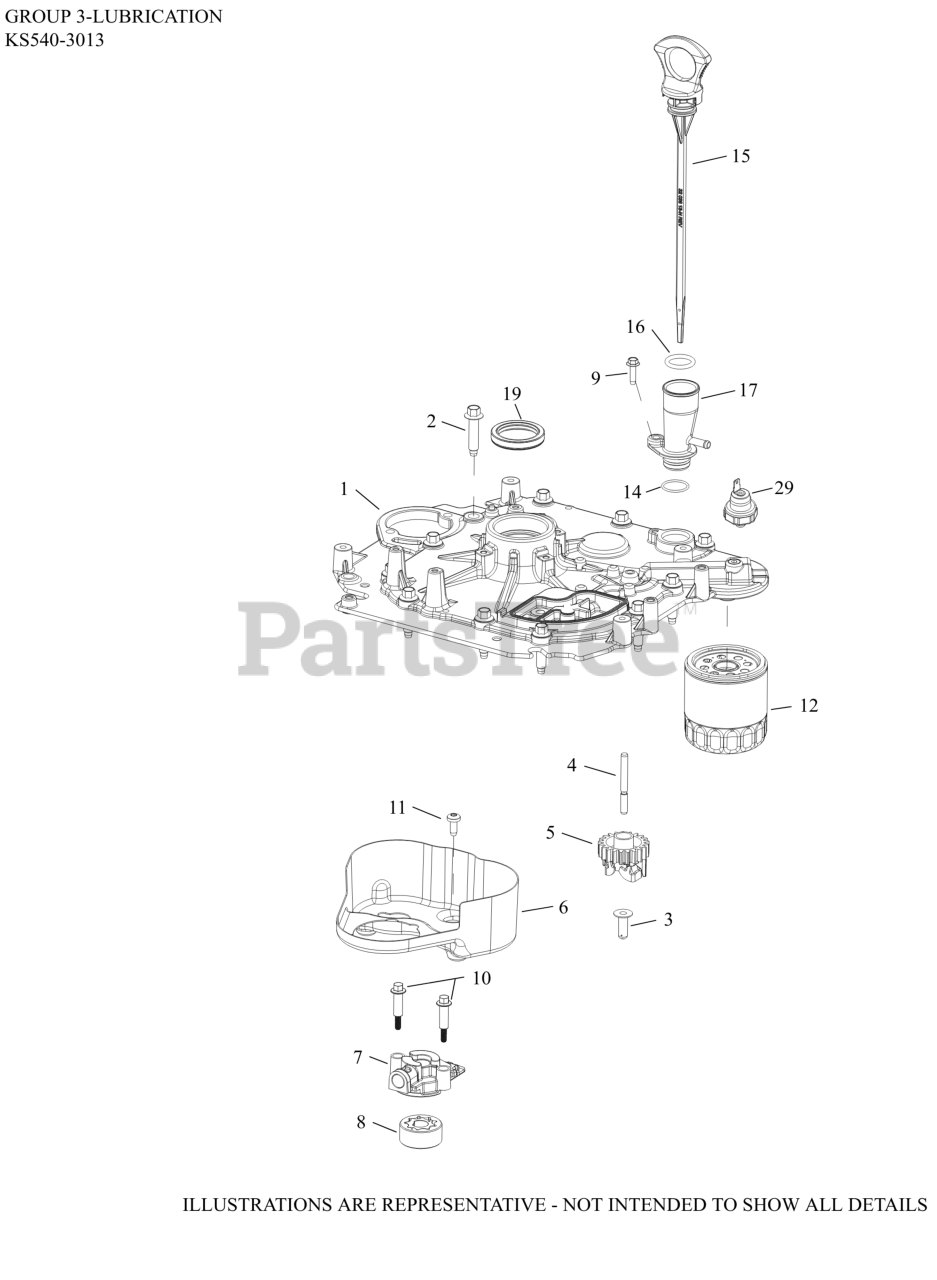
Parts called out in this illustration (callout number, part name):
1	PLATE, CLOSURE ASSY
2	SCREW, HEX FLANGE
3	PIN, GOVERNOR REGULATING
4	SHAFT, GOVERNOR CROSS
5	KIT, GOVERNOR GEAR
6	BAFFLE, OIL
7	HOUSING, OIL PUMP ASSY
8	PUMP ASSY, OIL
9	SCREW, THD FRM-USE 25 086 473-S
10	SCREW, SHOULDER THREAD FORMING
11	SCREW, THREAD FORMING
12	OIL FILTER
15	DIPSTICK, ASSY
17	TUBE, DIPSTICK ASSY
19	SEAL, OIL
NI	SENSOR, OIL PSI
